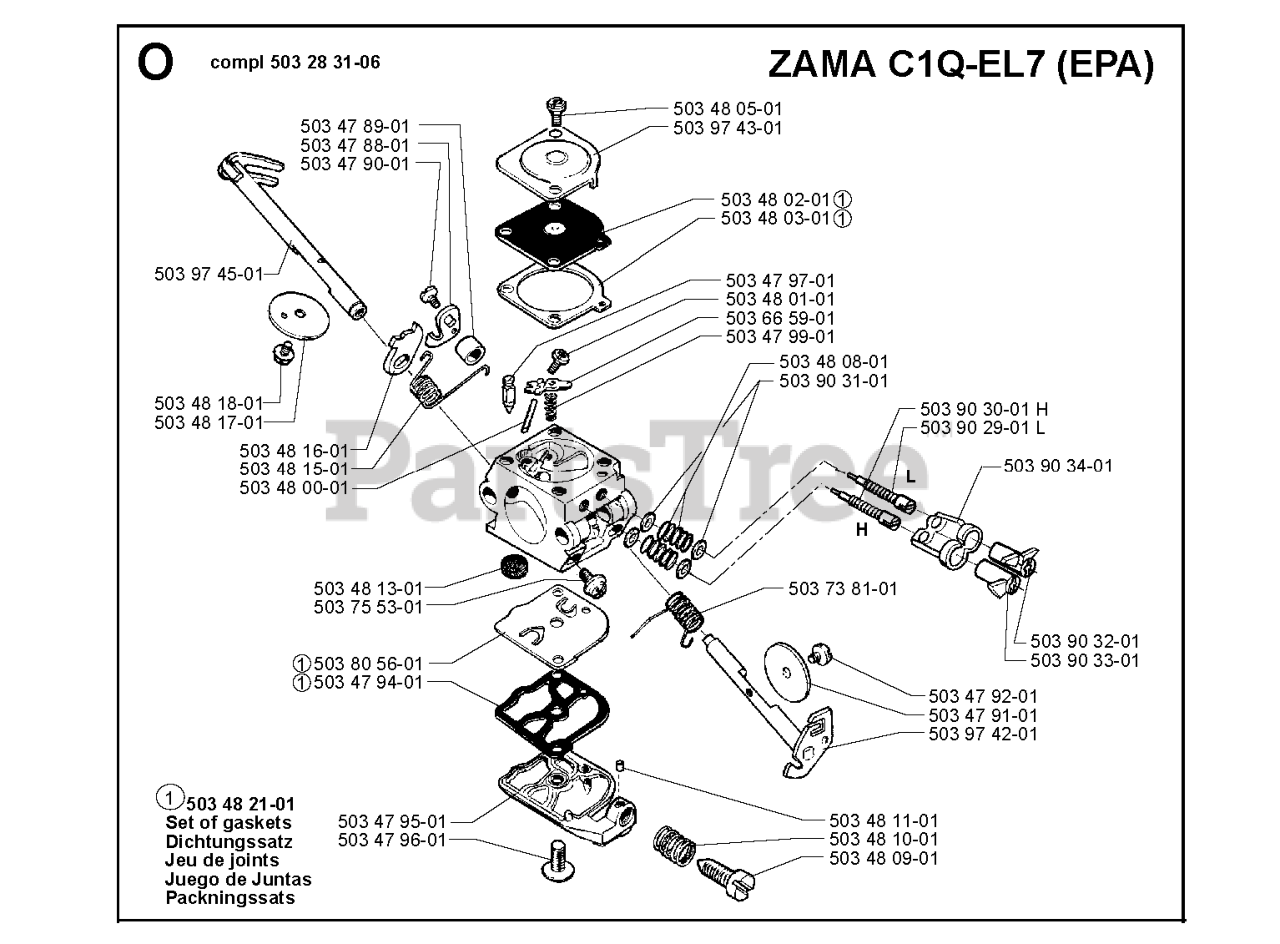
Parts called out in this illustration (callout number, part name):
3	Seals
9	Gaskets
20	Seals
22	Screws
121	Carburetors
